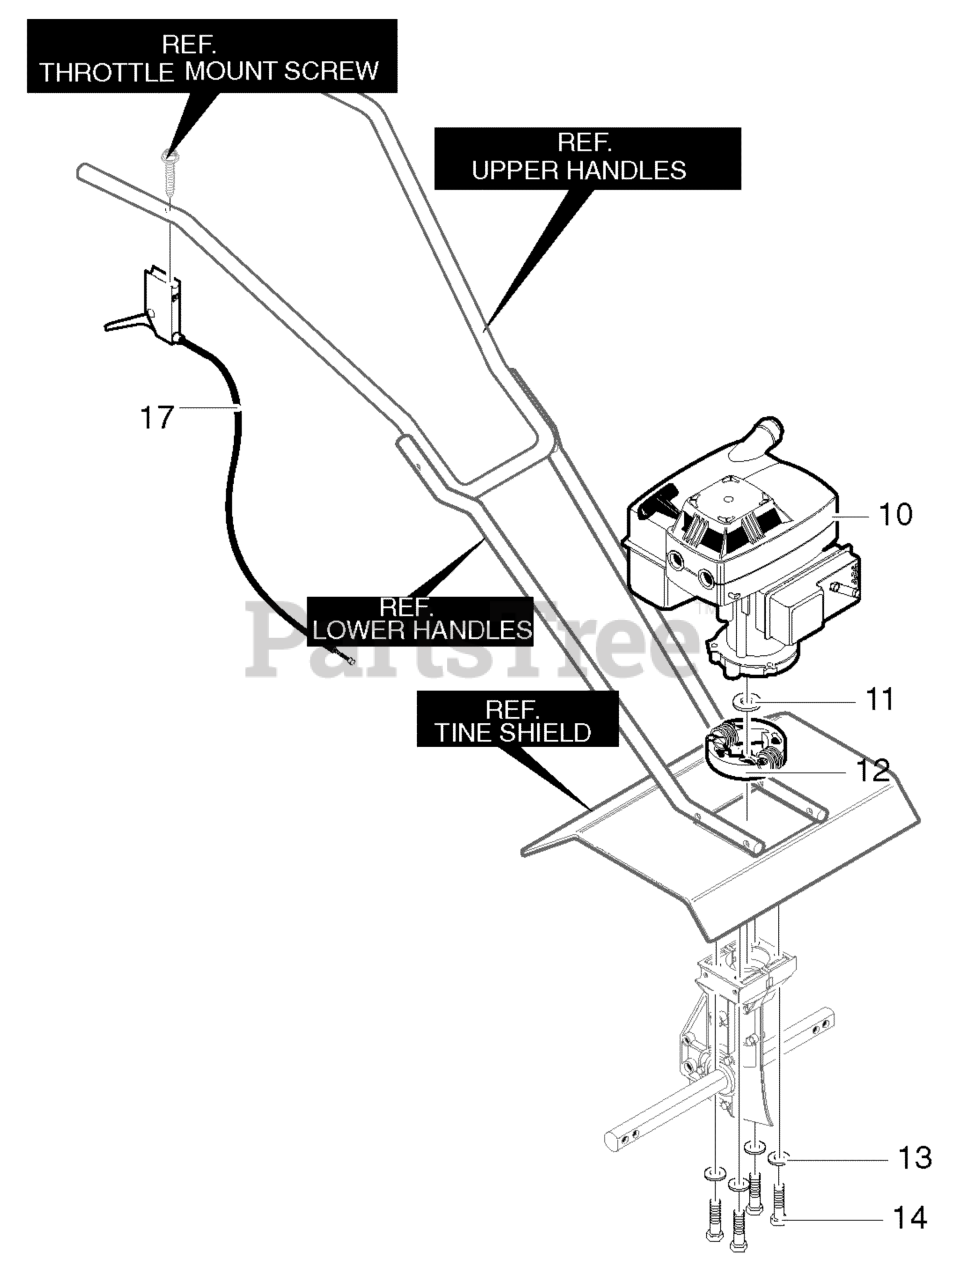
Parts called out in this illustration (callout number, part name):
10	ENGINE (2.0 HP)
11	WASHER, Flat
17	CABLE, Throttle
